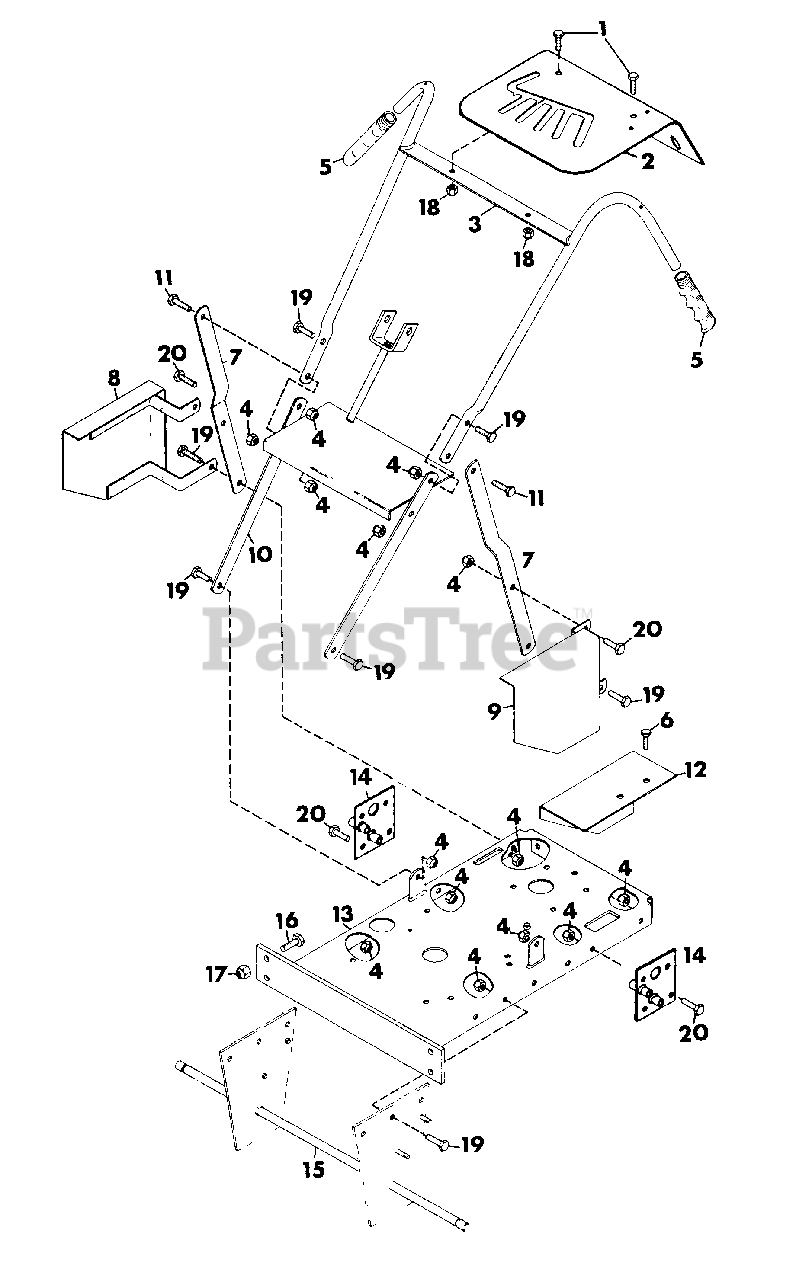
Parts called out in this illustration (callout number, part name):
1	BOLT, HEX 5/16-18X1.00
2	PLATE, INSTRUCTION
3	WELDMENT, HANDLEBAR
4	NUT, LOCK 3/8-16
5	GRIP, HAND
6	BOLT, SELF-TAPPING 5/16-18X.50
7	BRACE, HANDLEBAR SUPPORT
8	WELDMENT, BELT GUARD R.H.
9	WELDMENT, BELT GUARD L.H.
10	WELDMENT, HANDLE BAR SUPPORT
11	BOLT, HEX 3/8-16X1.25
12	GUARD, TRANSMISSION CHAIN
13	WELDMENT, FRAME
14	WELDMENT, BEARING SUPPORT L.H.
15	WELDMENT, AXLE
16	BOLT, HEX 1/2-13X1.50
17	NUT, LOCK 1/2-13
18	NUT, LOCK 5/16-18
19	BOLT, HEX 3/8-16X1.00
20	BOLT, HEX 3/8-16X.75
